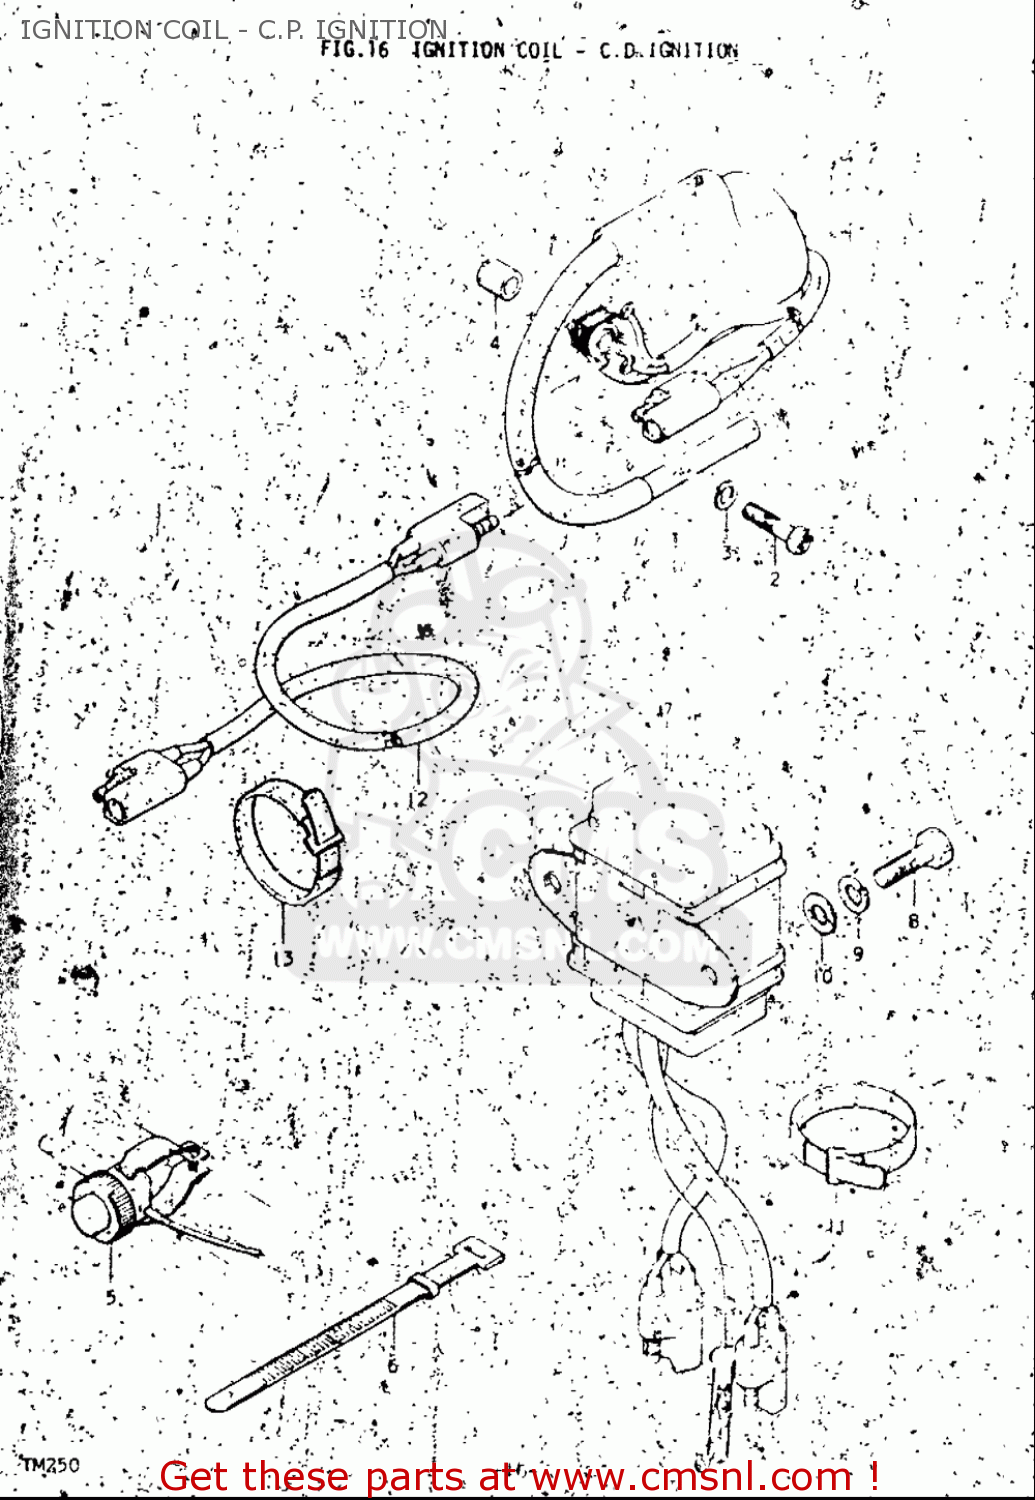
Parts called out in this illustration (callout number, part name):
1	COIL ASSY,IGNITION
2	SCREW
3	WASHER,LOCK
5	SWITCH ASSY,ENGINE STOP
6	CLAMP(L:120)
8	BOLT(6X20)
9	WASHER,LOCK
10	WASHER
11	CLAMP
13	CLAMP
